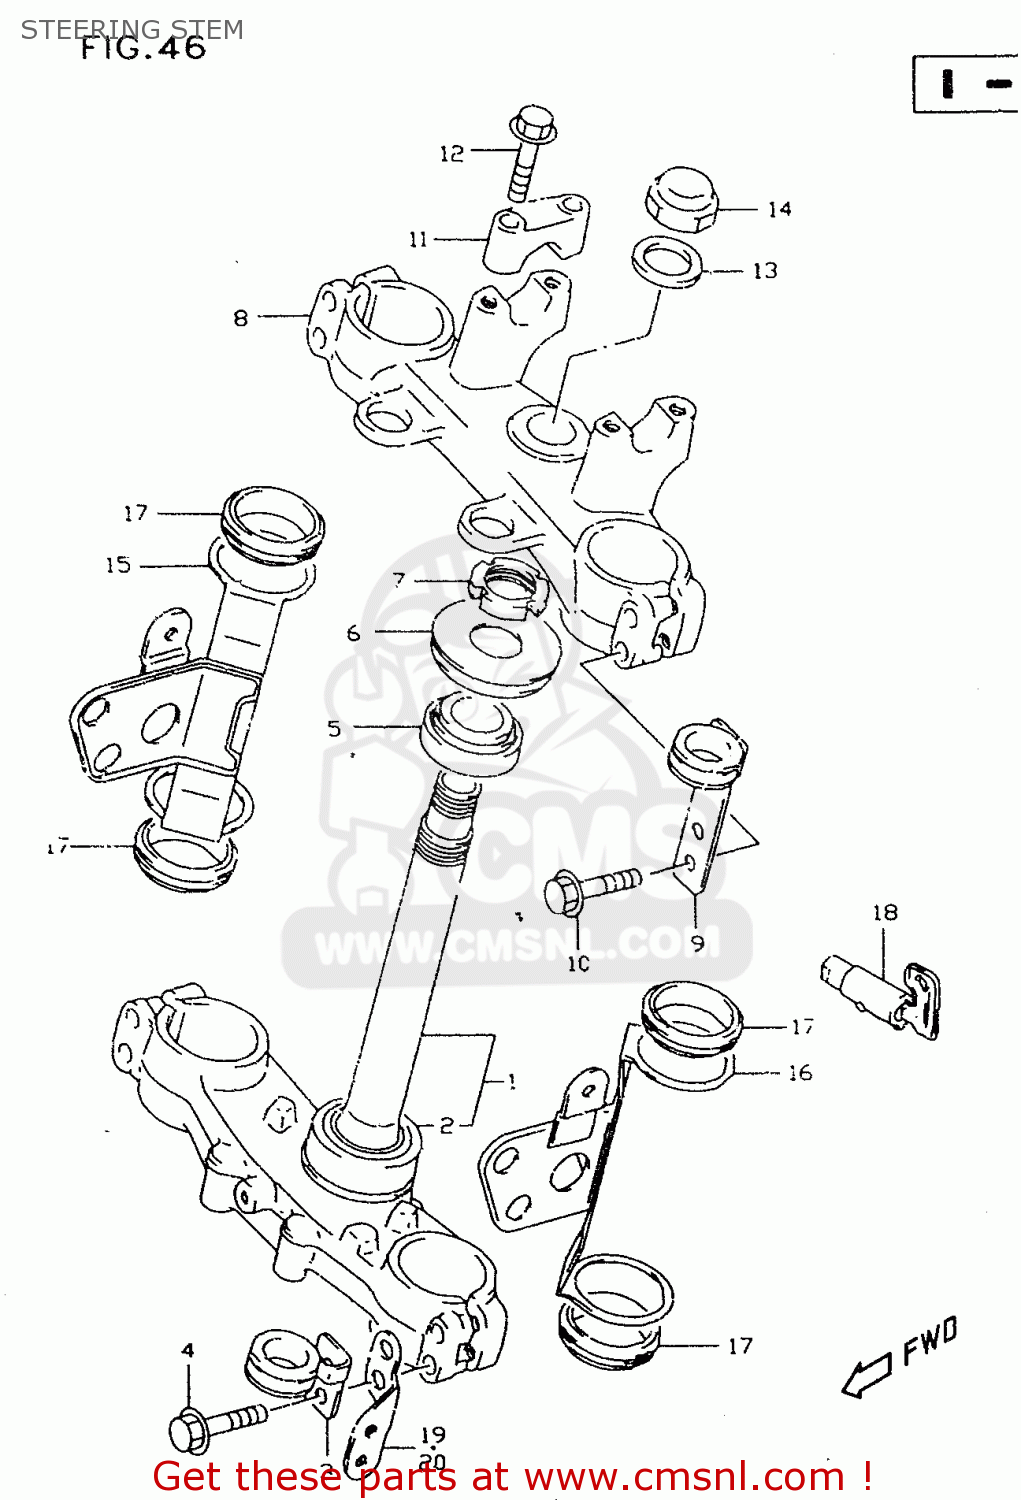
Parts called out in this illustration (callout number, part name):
1	STEM,STEERING
2	BEARING(30X55X17)
3	GUIDE,CABLE LWR,L
4	BOLT
5	BEARING(25X47X15)
6	SEAL,STEERING UPR DUST
7	NUT,STEERING STEM
8	HEAD,STEERING STEM
9	GUIDE,CABLE,LEFT,UPPER
10	BOLT
11	HOLDER,HANDLE UPR
12	BOLT
13	WASHER
14	NUT,CAP
15	BRACKET,HEADLAMP HOUSING,R
16	BRACKET,HEADLAMP HOUSING,L
17	DAMPER,HEADLAMP HSG BRACKET
18	LOCK ASSY,STEERING(NEIMAN)
19	BRACKET,FRONT SIDE REFLECTOR
20	BRACKET,FR SIDE REFLECTOR,L
